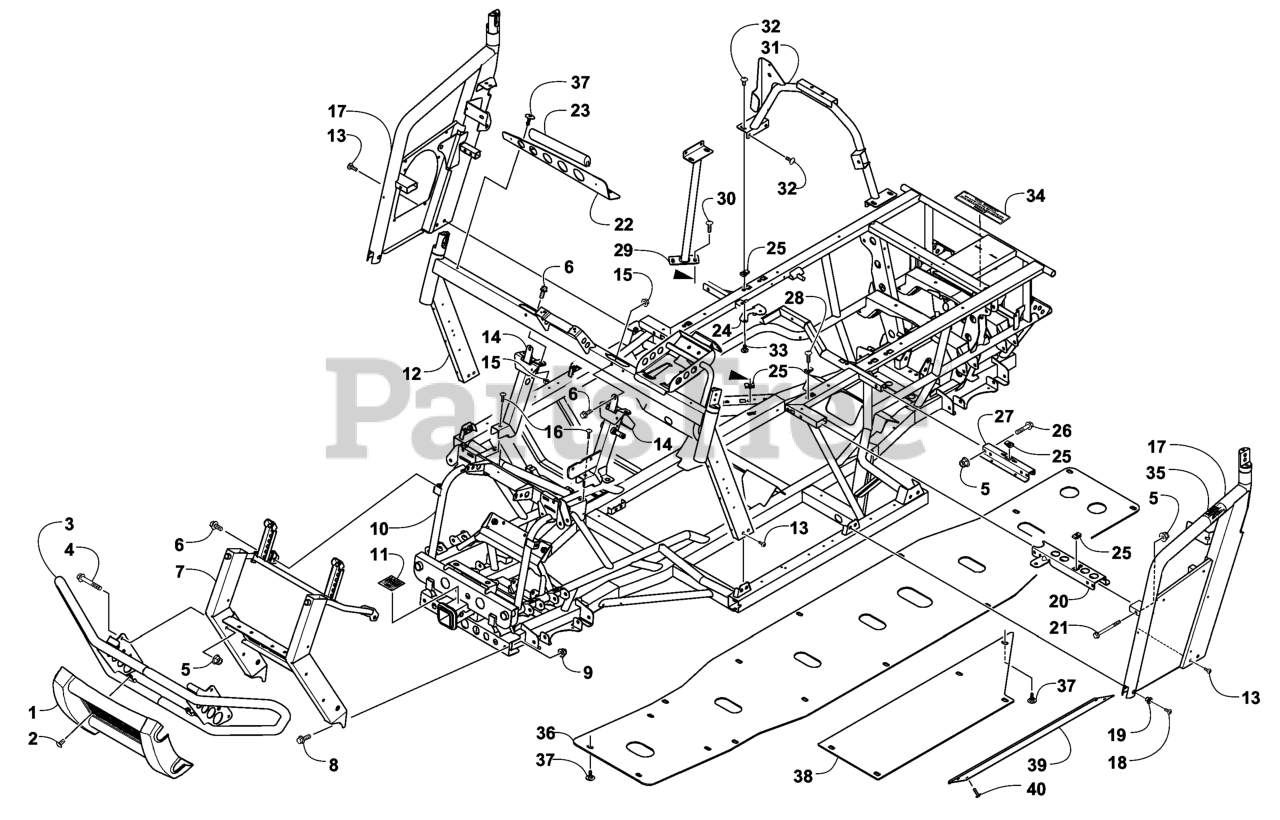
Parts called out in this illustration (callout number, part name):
1	FASCIA-BUMPER, FRONT
2	SCREW-TSPRH
3	BUMPER-PUSH
4	SCREW-HFH
5	NUT-HHF, LOCK, (NI)
6	SCREW-HFH
8	SCREW-HFH
9	NUT-HHF, LOCK (NI)
10	BELT,MAIN DRIVE BLADES
11	DECAL-WARNING, TOWING
12	SUPPORT-STEERING
13	SCREW-TSPRH
14	BRACKET-SUPPORT, STEERING
15	NUT-HHF
17	SUPPORT-ARM, RH
17	SUPPORT-ARM, LH
18	SCREW-TSTH
19	SPACER-STEEL
20	BRACKET-SEAT SUPPORT,FRON
21	SCREW-HFH
22	BRACKET-SUPPORT, HOOD (RH
22	BRACKET-SUPPORT, HOOD (LH
23	TRIM-EDGE, RUBBER
24	BRACKET-AIR INTAKE
25	CLIP-U NUT
26	SCREW-HFH
27	BRACKET-SEAT SUPPORT,REAR
28	SCREW-TSPRH
29	TUBE-SUPPRT
30	SCREW-TSPRH
31	SUPPORT-REAR CANOPY
32	SCREW-TSPRH
34	DECAL-WARNING, TOWING
35	DECAL-WARNING, ROPS
36	SKIDPLATE-MAIN
37	SCREW-SELF TAP
38	SKIDPLATE-SIDE
39	PLATE-SKID, SIDE
40	SCREW,MAC-TSBWH
